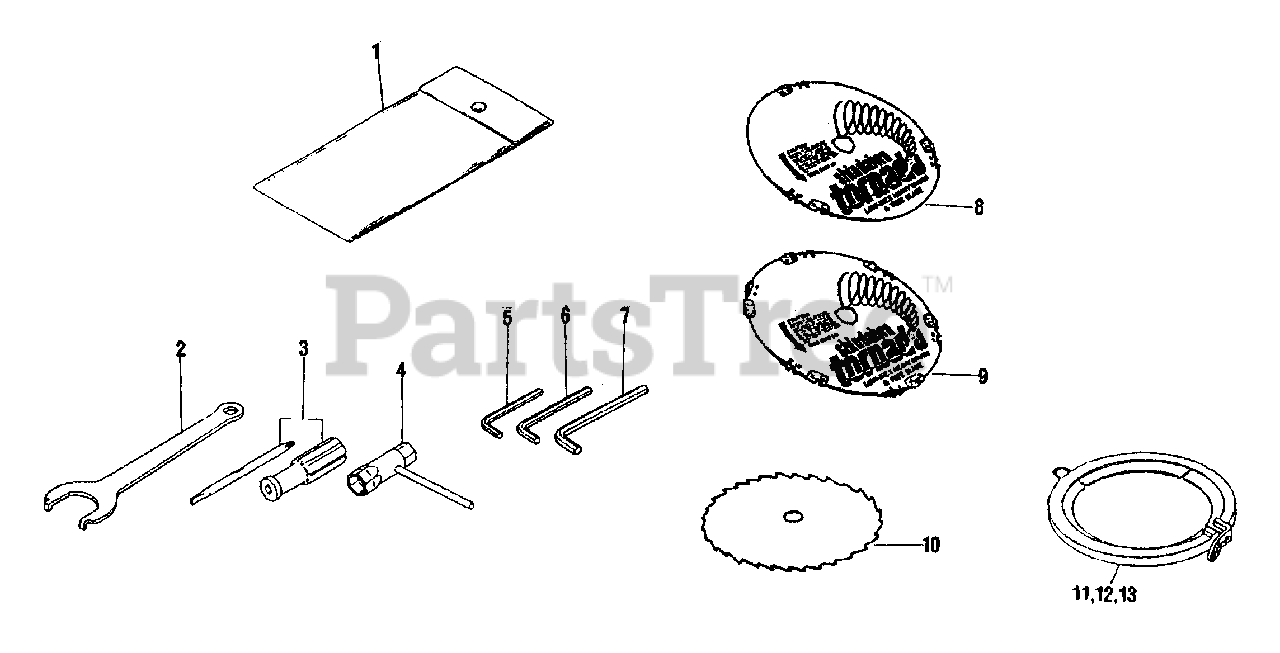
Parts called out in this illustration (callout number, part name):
1	BAG, TOOL
2	SPANNER
3	SCREWDRIVER
4	WRENCH, SPARK PLUG -- 17×9 MM
5	WRENCH - 3
6	WRENCH - 4
7	WRENCH - 5
8	BLADE - 6 TOOTH -- 9" TORNADO
9	BLADE - 12 TOOTH -- 9" TORNADO
10	BLADE - 30 TOOTH -- 9"
11	COVER - 8"
12	COVER- 9"
13	COVER - 10"
